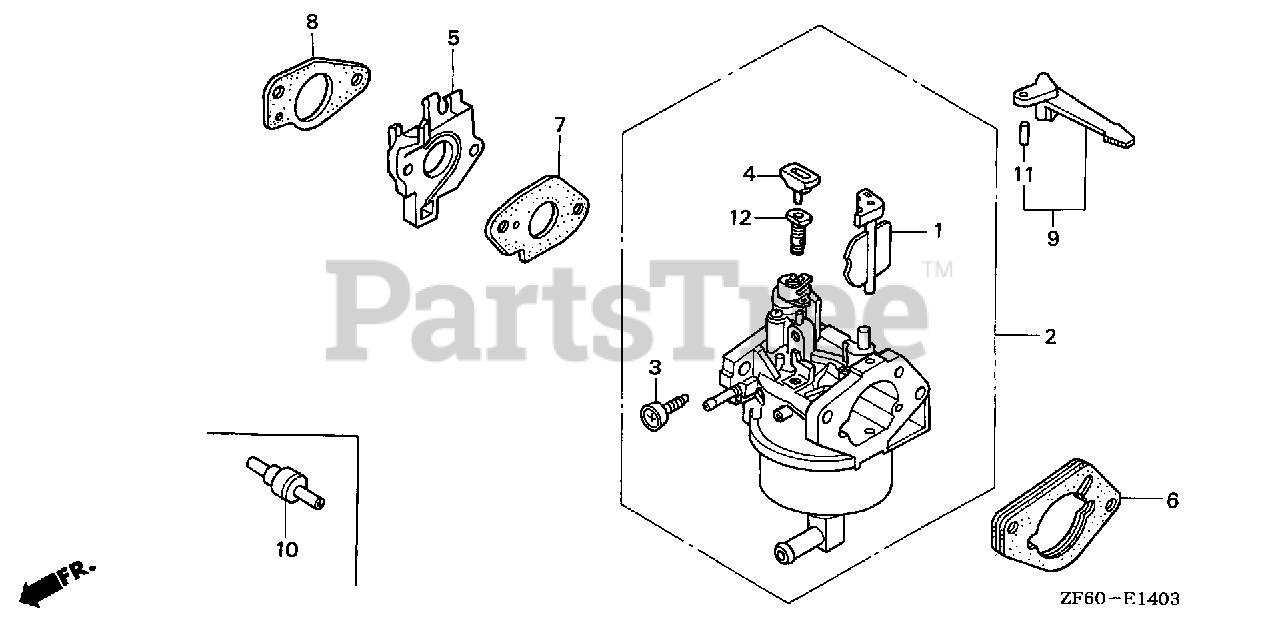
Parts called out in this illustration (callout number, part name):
2	CARBURETOR ASSY. (BEL5A A)
3	SCREW, THROTTLE STOP
4	COLLAR, SETTING
5	INSULATOR, CARBURETOR
6	SPACER, CARBURETOR
7	GASKET, CARBURETOR
8	GASKET, INSULATOR
9	LEVER, CHOKE (STD)
10	VALVE, DASHPOT CHECK
11	PIN, SPRING (2X12)
12	JET, PILOT (#45)
